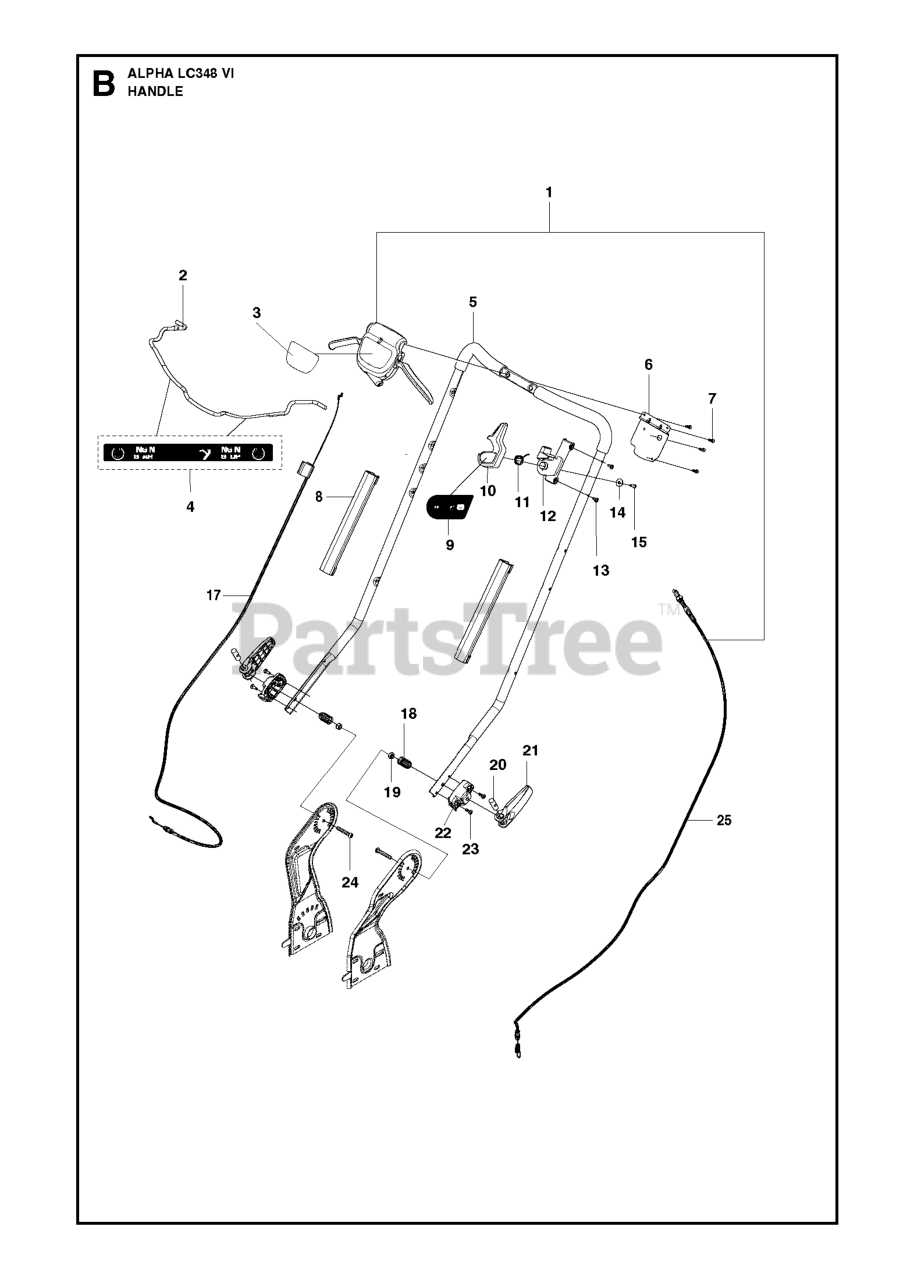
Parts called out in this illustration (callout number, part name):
13	SCREW ITXPANTT M5X10 ZPB (A00
14	WASHER - 26X6.5X1.6
19	LOCKNUT M8
